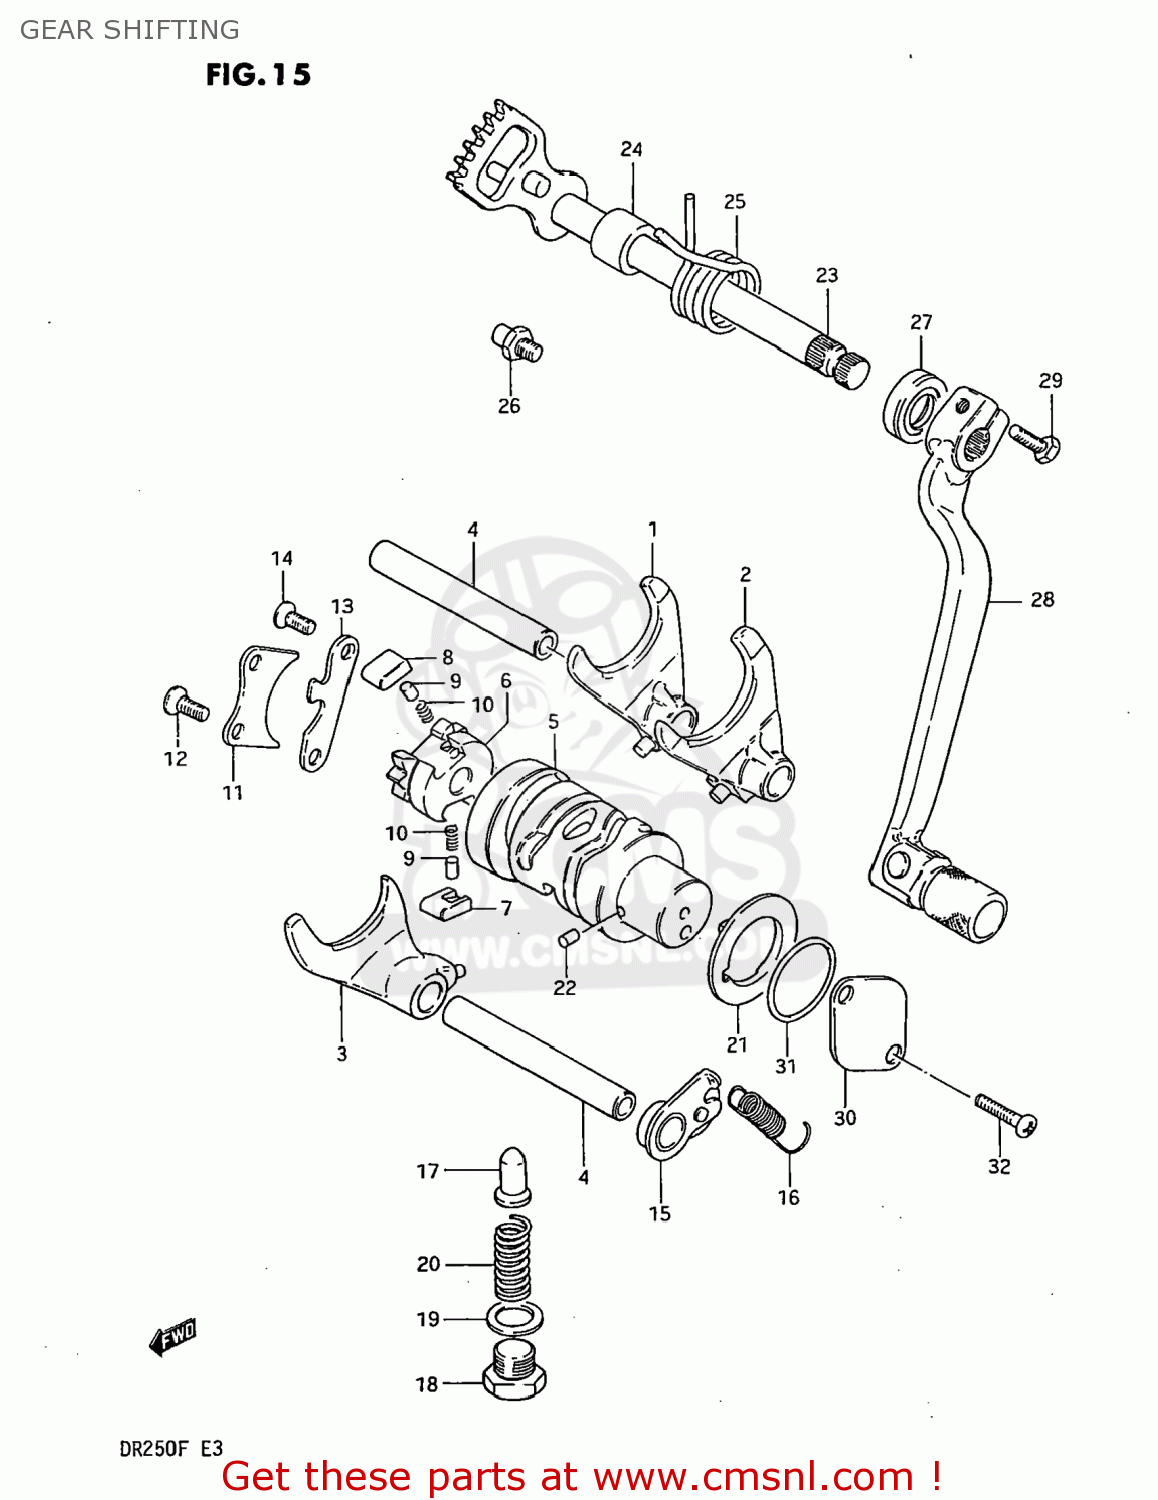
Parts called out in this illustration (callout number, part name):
1	FORK,GEAR SHIFT NO.1
2	FORK,GEAR SHIFT
3	FORK,GEAR SHIFT NO.3
4	SHAFT,GEAR SHIFT FORK
5	CAM,GEAR SHIFT
6	GEAR,GEARSHIFT CAM DRIVE
7	PAWL,GEAR SHIFT NO.1
8	PAWL,GEAR SHIFT NO.2
9	PIN(5X8)
10	SPRING
11	LIFTER,GEAR SHIFT PAWL
12	SCREW
13	GUIDE,GEAR SHIFT CAM
14	SCREW
15	STOPPER,GEAR SHIFT CAM
16	SPRING
17	STOPPER,GEAR SHIFT CAM NO.2
18	PLUG (14X12)
19	GASKET(14X19.2X2) (NAS)
20	SPRING
21	PLATE,GEAR SHIFT CAM STOPPER
22	PIN 4X6
23	SHAFT,GEAR SHIFT
24	SPACER(12X20X15.3)
25	SPRING
26	STOPPER,GEAR SHIFT CAM
27	OIL SEAL
28	LEVER ASSY,GEAR SHIFT
29	BOLT
30	CAP,GEAR SHIFT CAM PIVOT
31	O-RING (D:2.4 ID:26.2)
32	SCREW
